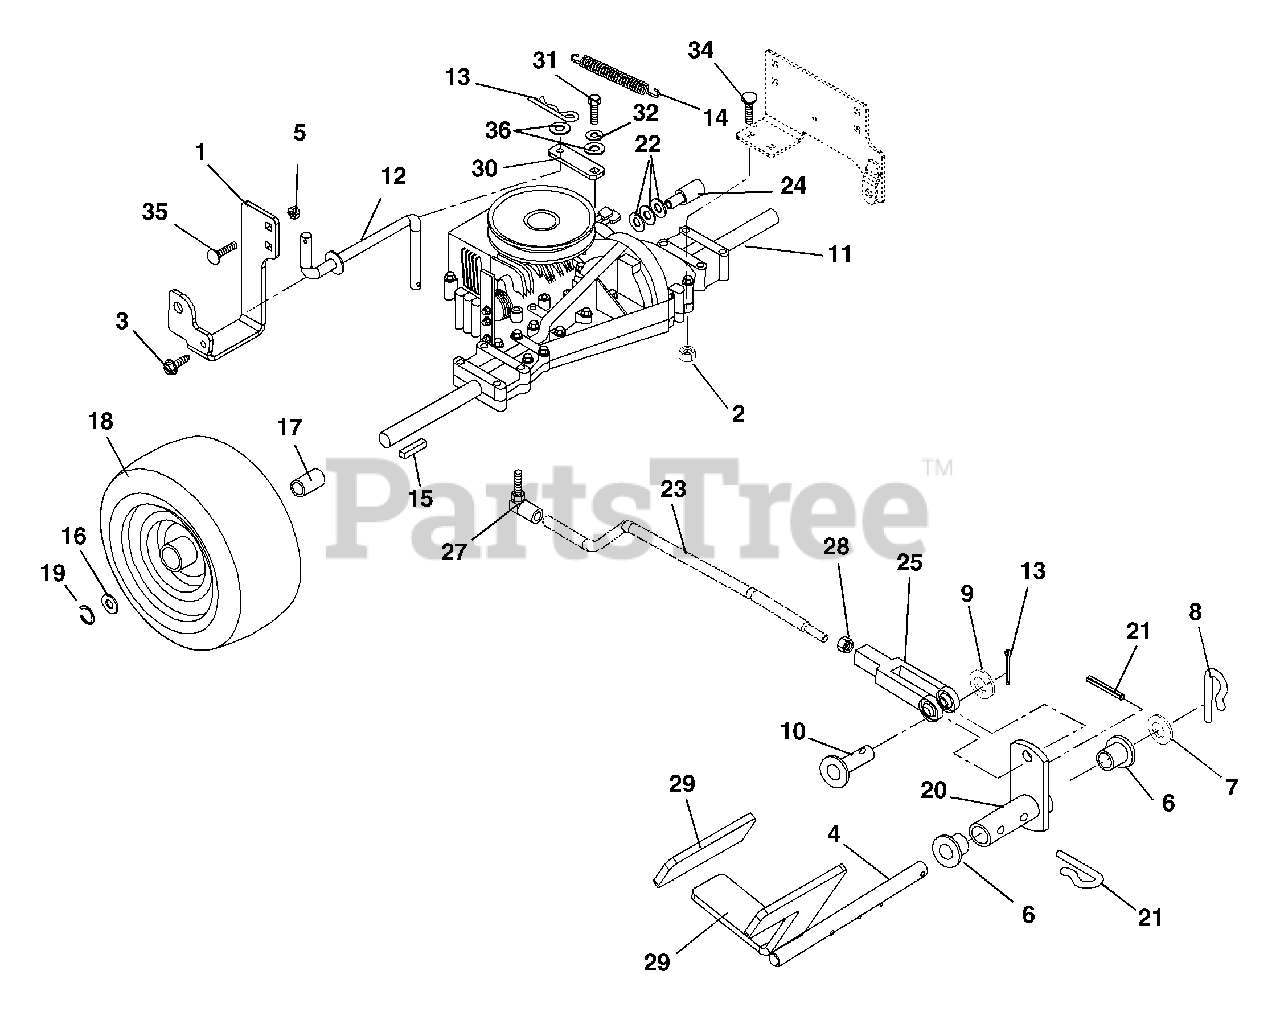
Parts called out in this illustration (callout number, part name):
1	Support, Transmission
2	Nut, Flange .50-13
3	Screw-Tapping .31-18 x .75 Hex Washer Head
4	Weldment, Forward and Reverse Pedal
5	Nut, Locking Top Flange .38-16
6	Bushing, Flange .515 x .75 x .745 x 1.00
7	Washer, Flat Steel .505 x 1.00 x .062
8	Clip, Spring
9	Washer, Flat Steel .38 x .87 x .179
10	Pin, Clevis .31 x .822
11	Transmission Peerless Hydro
12	Rod, Transmission Disconnect
13	Pin, Hair
14	Spring, Tension .043 x .44 x 3.31
15	Key, Square .188 x 2.0 x .188
16	Washer, Flat Steel .755 x 1.25 x .125
17	Spacer, Wheel .75 x 1.00 x 1.25
18	Assembly, Tire and Wheel 16 x 6.5 x 8 (060, 062)
18	Assembly, Tire and Wheel 480 x 8 (064)
18	Tire 16 x 6.50-8 2 Pulley
19	Ring, Retaining External .75 x .05
20	Weldment, Shift Rod and Hub
21	Pin, Center .12 x 1.00 Extended Prong Square Cut
22	Washer, Flat, Steel .50 x 1.00 x .062
23	Rod, Rear Engine Rider Shift
24	Trunnion
25	Yoke .31-24 x 2.250
26	Washer, Flat Steel .390 x .750 x .125
27	Ball Joint
28	Nut-Locking-Nylon .375-24 With Insert
29	Grip, Pedal
30	Tab, Transmission Disconnect
31	Bolt-Hex .25-28 x .75 Grade 5
32	Washer, Locking .25 x .062 Regular
33	Washer, Flat Steel .328 x 1.00 x .094
34	Bolt, Round Head Square Neck .31-18 x 2.50 Grade 5
35	Bolt, Round Head Square Neck .38-16 x .75 Grade 5
36	Washer, Flat Steel .38 x .875 x .083
